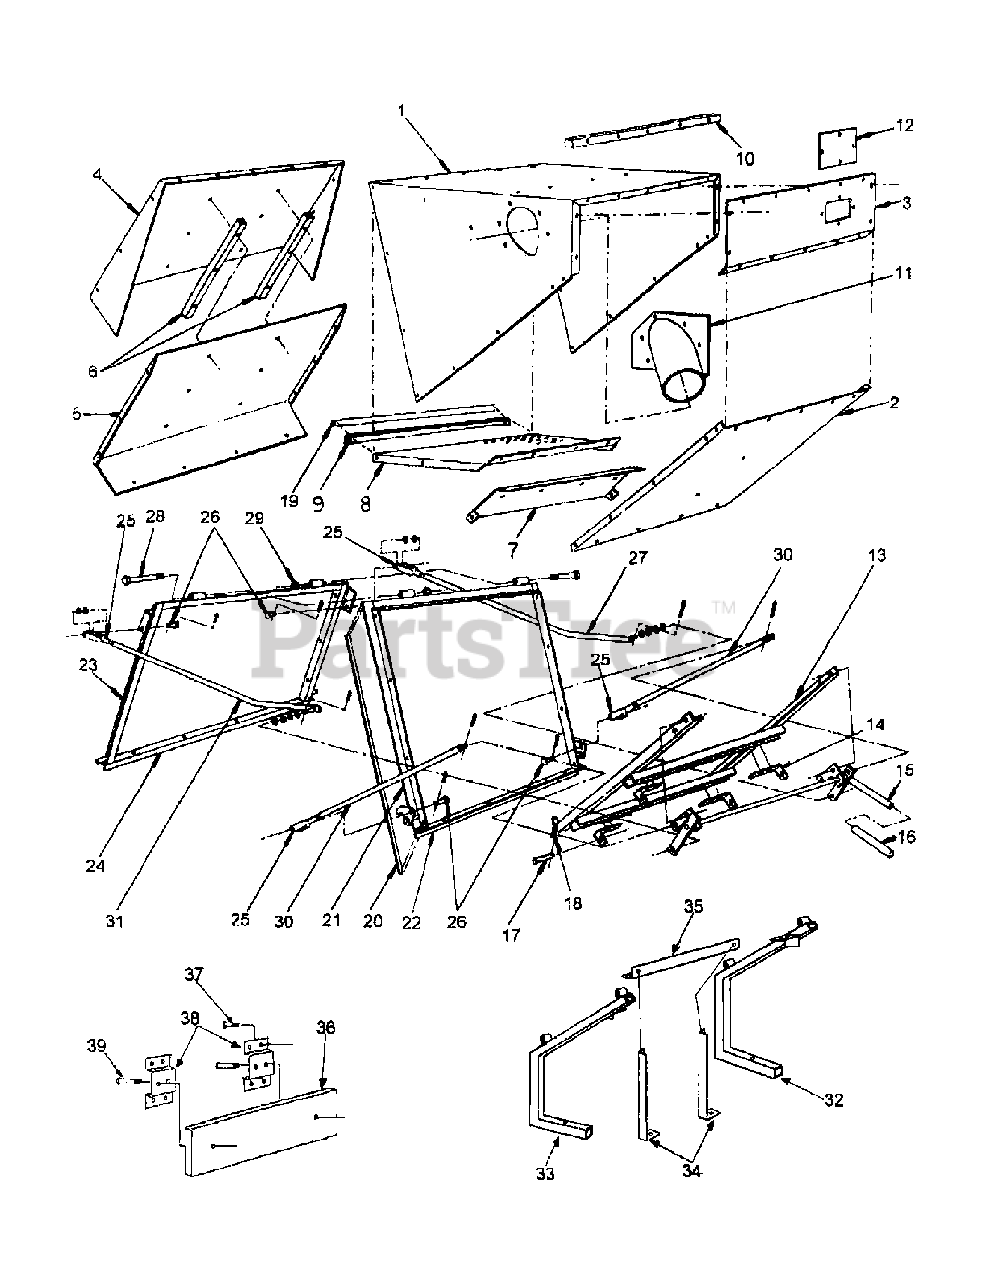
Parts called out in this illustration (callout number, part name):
1	Catcher Body
2	Catcher Box Bottom
3	Catcher Front
4	Outer Door Shell
5	Inner Door Shell
6	Door Vent Spacer
7	Intake Deflector
9	Rear Screen Support
10	Front Bumper
11	Intake Tube 6"
12	Viewing Window
13	Catcher Frame Base
14	Base Frame Tab
15	Lever Dump Assembly
16	Vinyl Grip 5"
17	Clevis Pin 1/2" x 3"
18	Hair Spring Cotter # 6
19	Rubber Seal
21	Catcher Frame Opening
22	Bottom Catcher Frame Opening
23	Catcher Door Frame
24	Bottom Door Frame
25	Adjustable Yoke End 3/8"-24
26	Clevis Pin 3/8" x 1-1/8"
27	Hinge Rod Left
28	1/2" x 5" Hex Head Bolt
29	1/2"-13 Nylock Nut
31	Hinge Rod Right
32	Catcher Mounting Left
33	Catcher Mounting Right
34	Catcher Mounting Support
36	Weight Bar
37	5/16"-18 x 1" Carriage Bolt
38	Weight Mounting Bracket
39	3/8"-16 x 4-1/2" Hex Head Bolt
